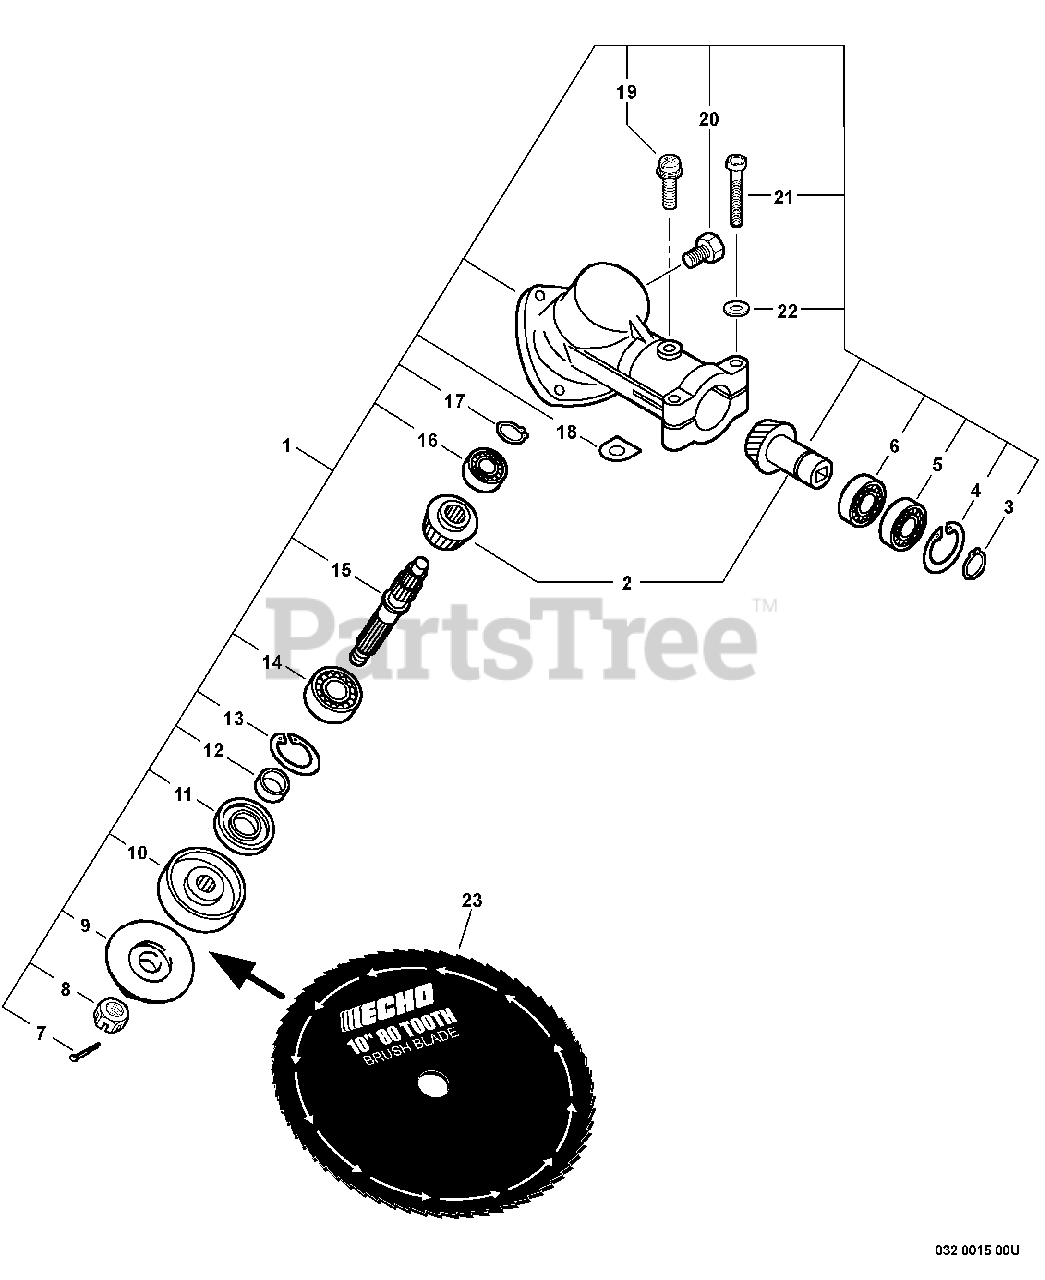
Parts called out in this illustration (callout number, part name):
1	GEAR CASE ASSY
2	GEAR SET
3	RING, SNAP Ø12
4	RING, SNAP 28
5	BEARING, BALL 6001
6	BEARING, BALL 6001
7	PIN, COTTER 2×22
9	PLATE, ADAPTOR - LOWER
10	PLATE, ADAPTOR - UPPER
11	SEAL, OIL 22
12	SPACER 11.8×15×9
13	RING, SNAP Ø32
14	BEARING, BALL - 6201 C3
15	SHAFT, GEAR
16	BEARING, BALL 6000
17	RING, SNAP Ø12
19	SCREW 5×10
20	BOLT M8×8
21	BOLT 5×40
22	WASHER, FLAT 5.5×10×0.8
23	BLADE, 10" 80 TOOTH
